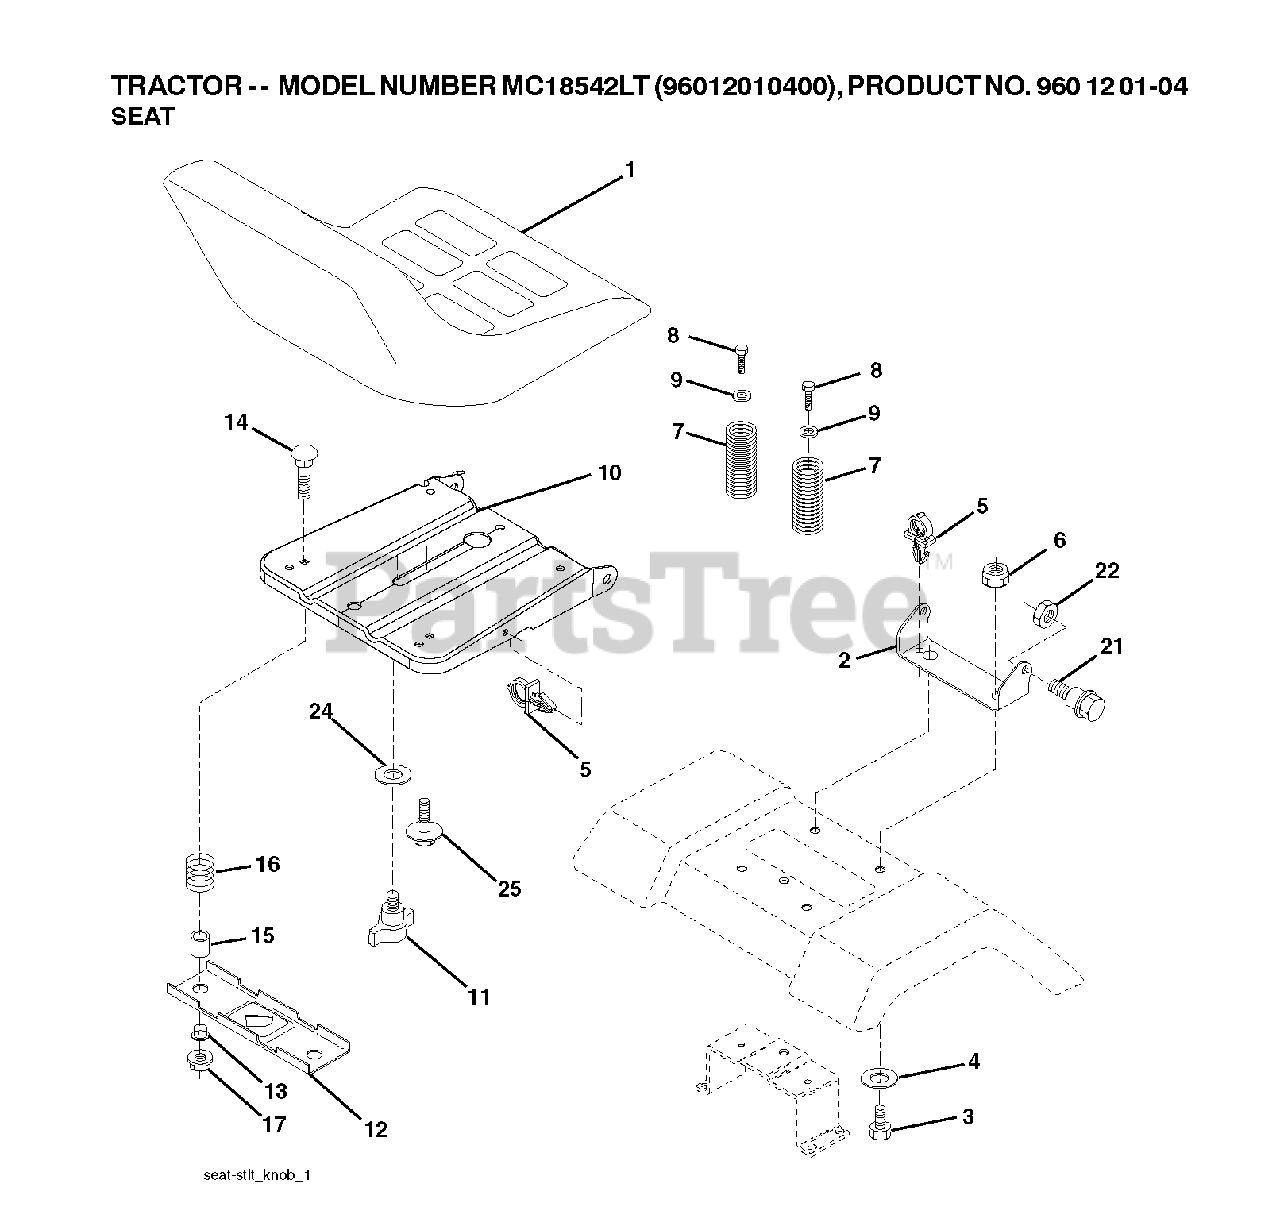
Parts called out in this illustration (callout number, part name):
1	SEAT.XG090.BLK.KB/BLT.NO-LOG
2	SEAT PIVOT BRKT
3	BOLT, HEX 3/8-16X1
4	WASHER PM
5	PUSH CLIP
6	NUT
7	SPRING COMPRESSION
8	SCREW 3/8-16X1
10	PAN.ASM.SEAT.1SLOT
12	BRKT.MNTNG.SWITCH.SEAT.BLACK
14	BOLT.ROUND.HEAD.SQUARE.NECK
15	SPACER SPLIT 28X.96
17	NUT T
21	BOLT.SHOULDER.5/16-18
22	NUT.71038.31-18.HEX.NYLOCK
23	BOLT.HEX.BLACK
25	BOLT,SHOULD
26	LOCKWASHER
